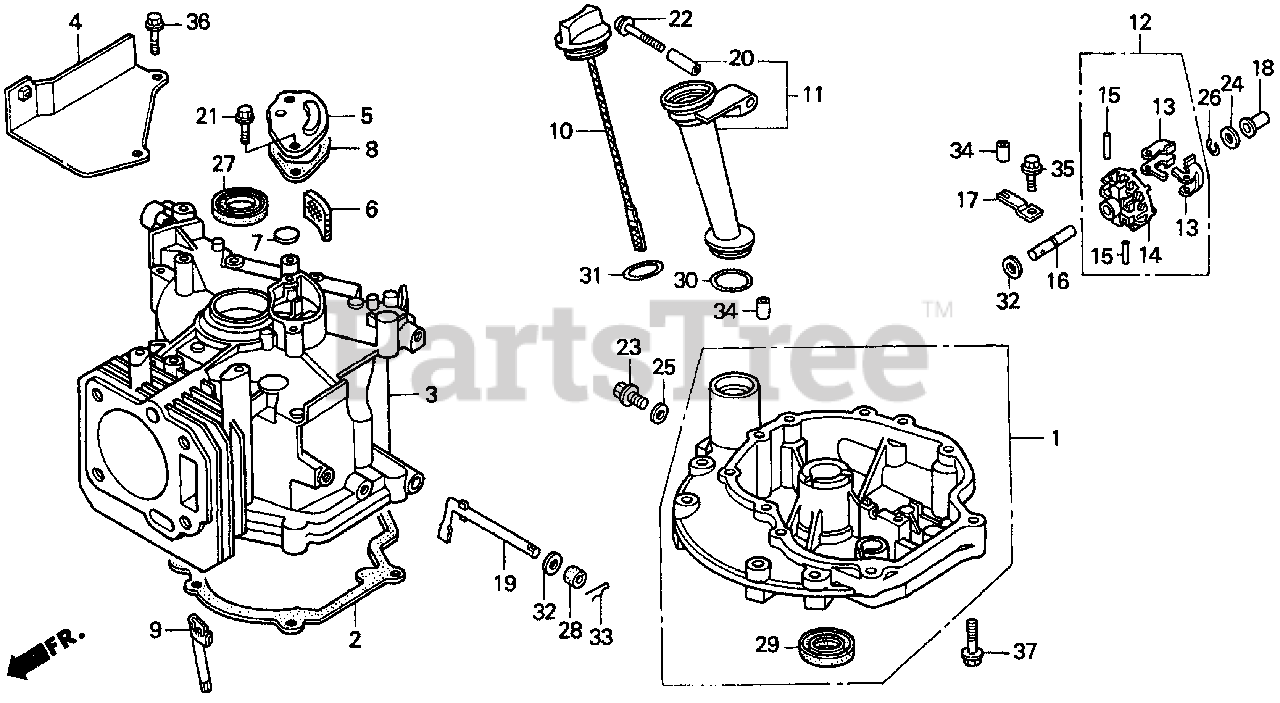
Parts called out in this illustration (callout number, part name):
1	PAN ASSY., OIL
2	GASKET, OIL PAN (HPE)
3	CYLINDER
4	PLATE, GUIDE
5	CAP, BREATHER CHAMBER
6	FILTER, BREATHER
7	VALVE, BREATHER
8	GASKET, BREATHER CHAMBER
9	PIPE, OIL DEFENSE
10	GAUGE, OIL LEVEL Use up to Engine SN 1257294.
11	EXTENSION, OIL FILLER (106MM)
12	GOVERNOR ASSY.
13	WEIGHT, GOVERNOR
14	HOLDER, GOVERNOR WEIGHT
15	PIN, GOVERNOR WEIGHT
16	SHAFT, GOVERNOR HOLDER
17	PLATE, GOVERNOR SHAFT HOLDER
18	SLIDER, GOVERNOR
19	SHAFT, GOVERNOR ARM
20	COLLAR, EXTENSION Use up to Engine SN 1257294.
21	BOLT, FLANGE (6X14)
22	BOLT, FLANGE (6X32)
23	BOLT, DRAIN PLUG
24	WASHER, THRUST (6MM)
25	WASHER, DRAIN PLUG (10.2MM)
26	CLIP, GOVERNOR HOLDER
27	OIL SEAL (22X35X6)
28	OIL SEAL (6X11X4)
29	OIL SEAL (25X38X7) (ARAI)
30	O-RING (22.5X2.2) Use from Engine SN 1257295.
31	O-RING (26X2.7)
32	WASHER, PLAIN (6MM)
33	PIN, LOCK (8MM)
34	PIN A, DOWEL (8X14)
35	BOLT, FLANGE (6X12) Use from Engine SN 2086984.
36	BOLT, FLANGE (6X20)
37	BOLT, FLANGE (6X28)
